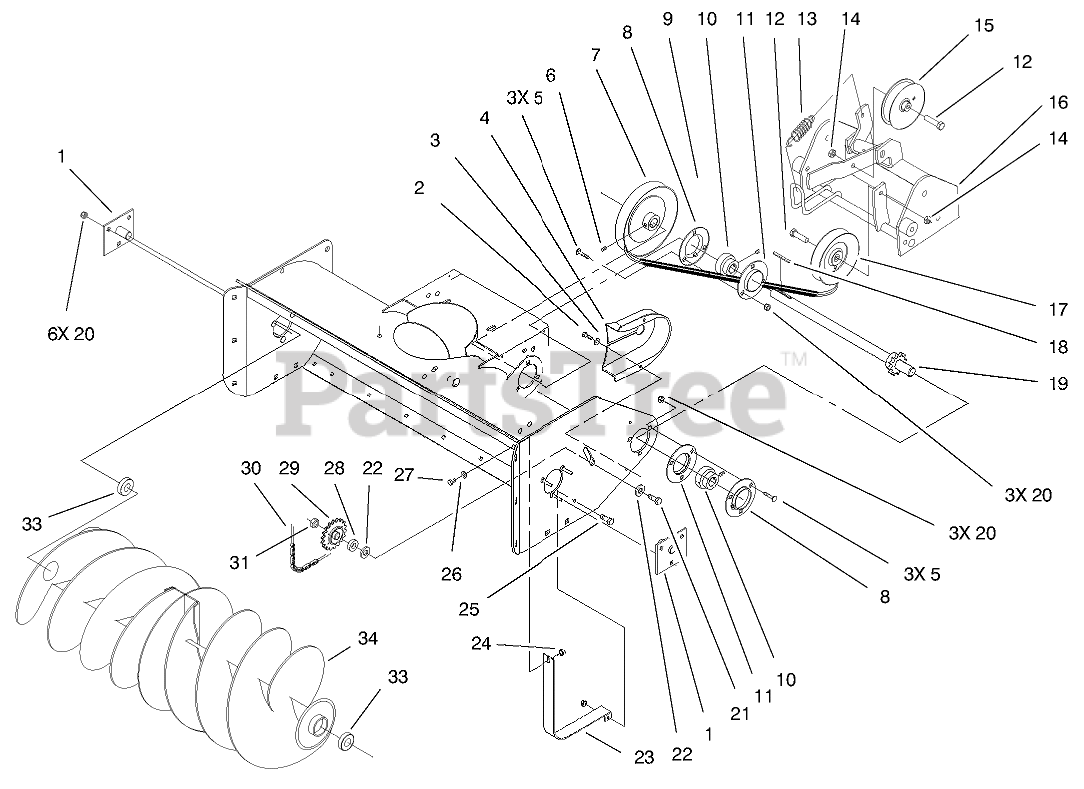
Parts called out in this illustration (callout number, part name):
1	SUPPORT
2	SCREW-HWH
3	WASHER-FLAT
4	GUARD-CHAIN
5	BOLT-CARR
6	SCREW-SQH
7	PULLEY
8	Flange
9	V-BELT
10	BEARING AND COLLAR
11	FLANGE-ZERK RELUBE
12	SCREW-HH
13	SPRING-EXTENSION
14	NUT-LOCK, NI
15	PULLEY-IDLER
16	FRAME-PULLEY
17	PULLEY-IDLER
18	KEY-STRAIGHT
19	SHAFT-DRIVE
20	NUT-LOCK, NI
21	SCREW-HH
22	WASHER-FLAT
23	GUARD-INNER
24	NUT-KEPS
25	SCREW
26	WASHER-FLAT
27	SCREW-HH
28	SPACER
29	Idler Sprocket
30	CHAIN
31	NUT-LOCK, NI
33	BEARING-BALL
34	Auger
